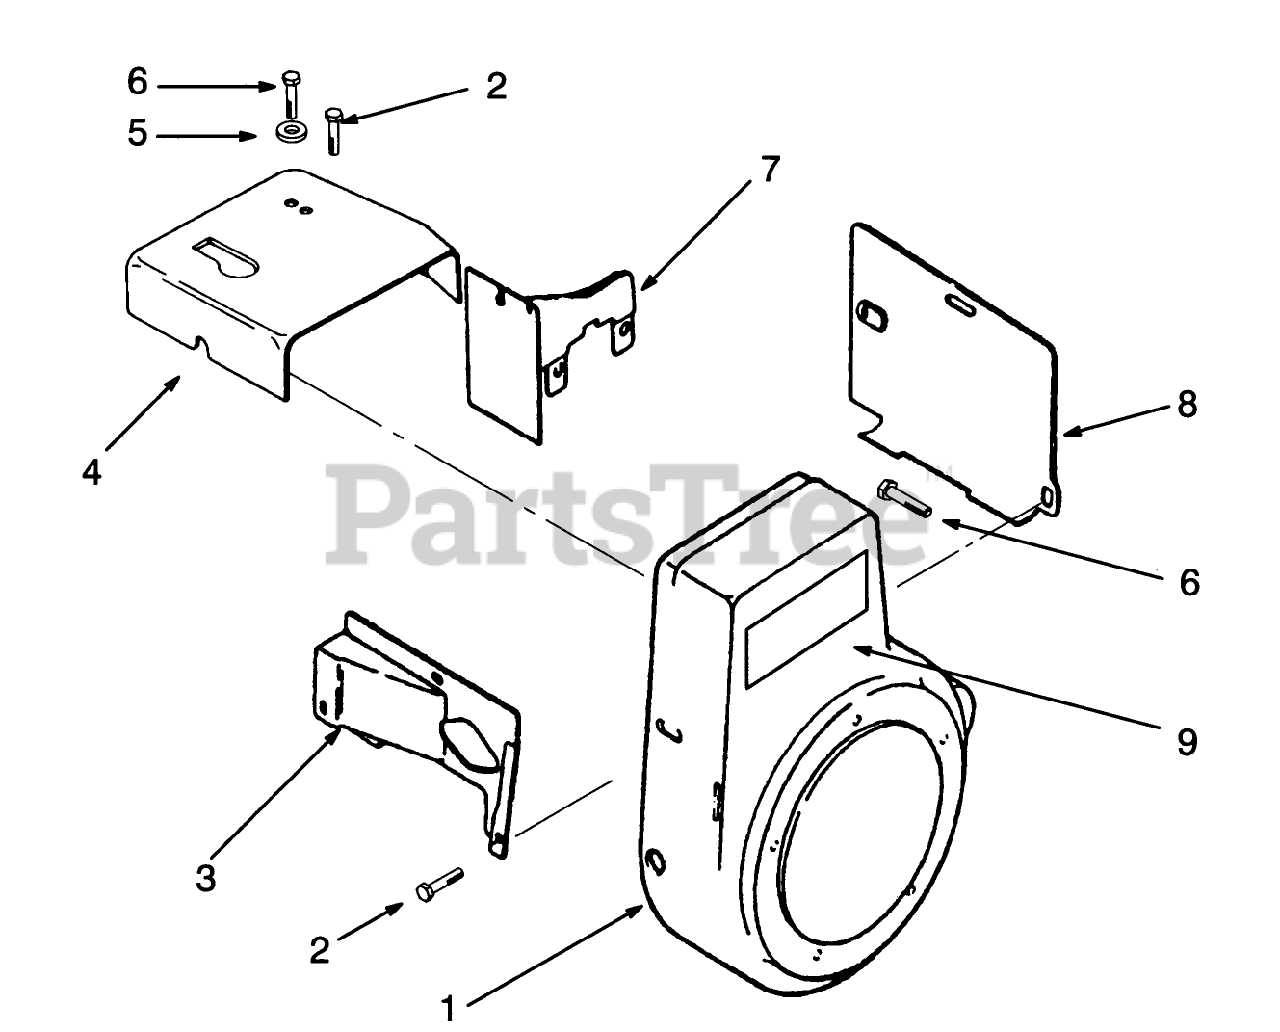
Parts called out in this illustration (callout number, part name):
1	KOHLER 47-027-42
2	KOHLER 52-086-11
3	KOHLER 47-063-06
4	KOHLER 47-063-09
5	KOHLER X-25-53
6	KOHLER 47-086-08
7	KOHLER 47-063-07
8	KOHLER 47-063-10
9	Decal-HP
